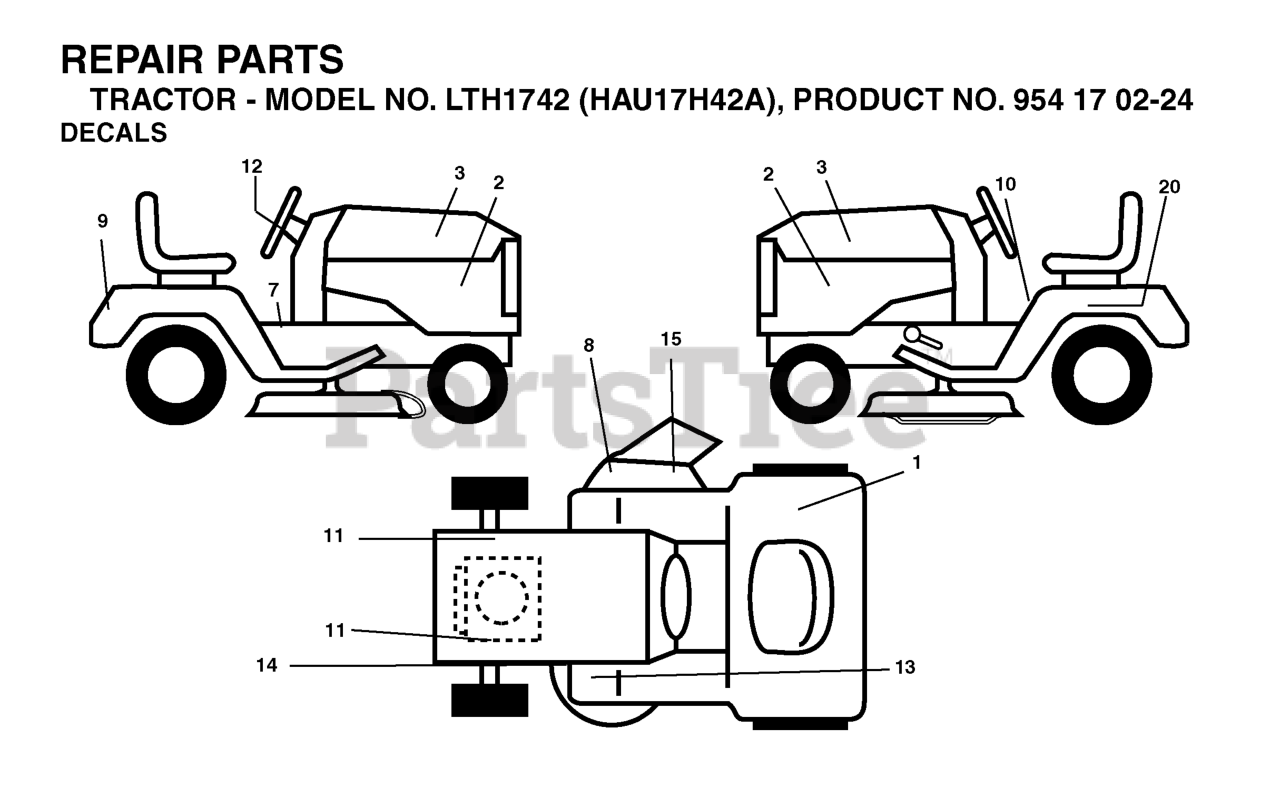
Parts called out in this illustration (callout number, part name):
1	DECAL
3	DECAL.HOOD.HUSQVARNA.INTERNATI
7	DECAL PARK BRAKE
8	DECAL.INTERNATIONL.CUTFINGER
10	DECAL READ OWNER'S MAN SYMS
12	DECAL.STEERING.HUSQ.BLUE
13	DECAL
14	DECAL V BELT SCHEMATIC
15	DECAL DECK "B" 42"
20	DECAL BTRY SYMBOLS
